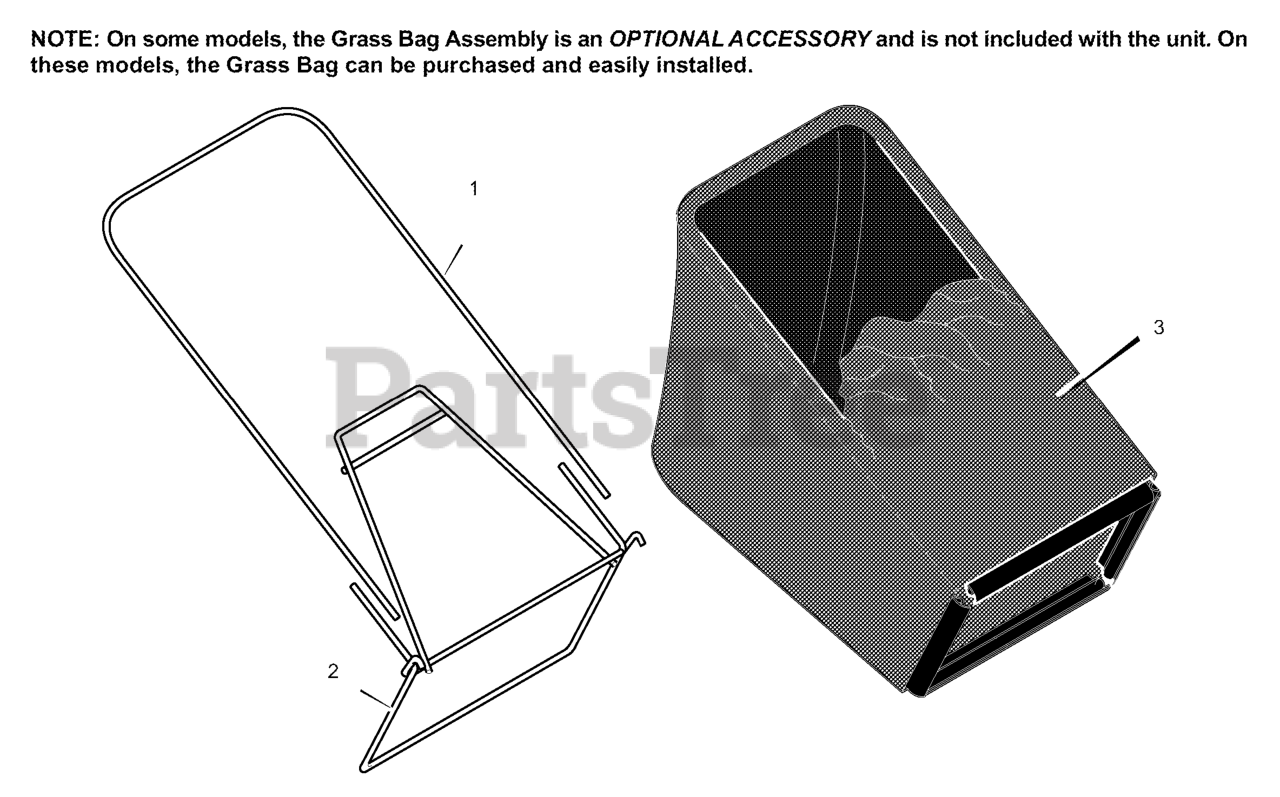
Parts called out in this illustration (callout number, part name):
1	Tube, Bag
2	Frame Assembly
3	Bag, Cloth - Black
